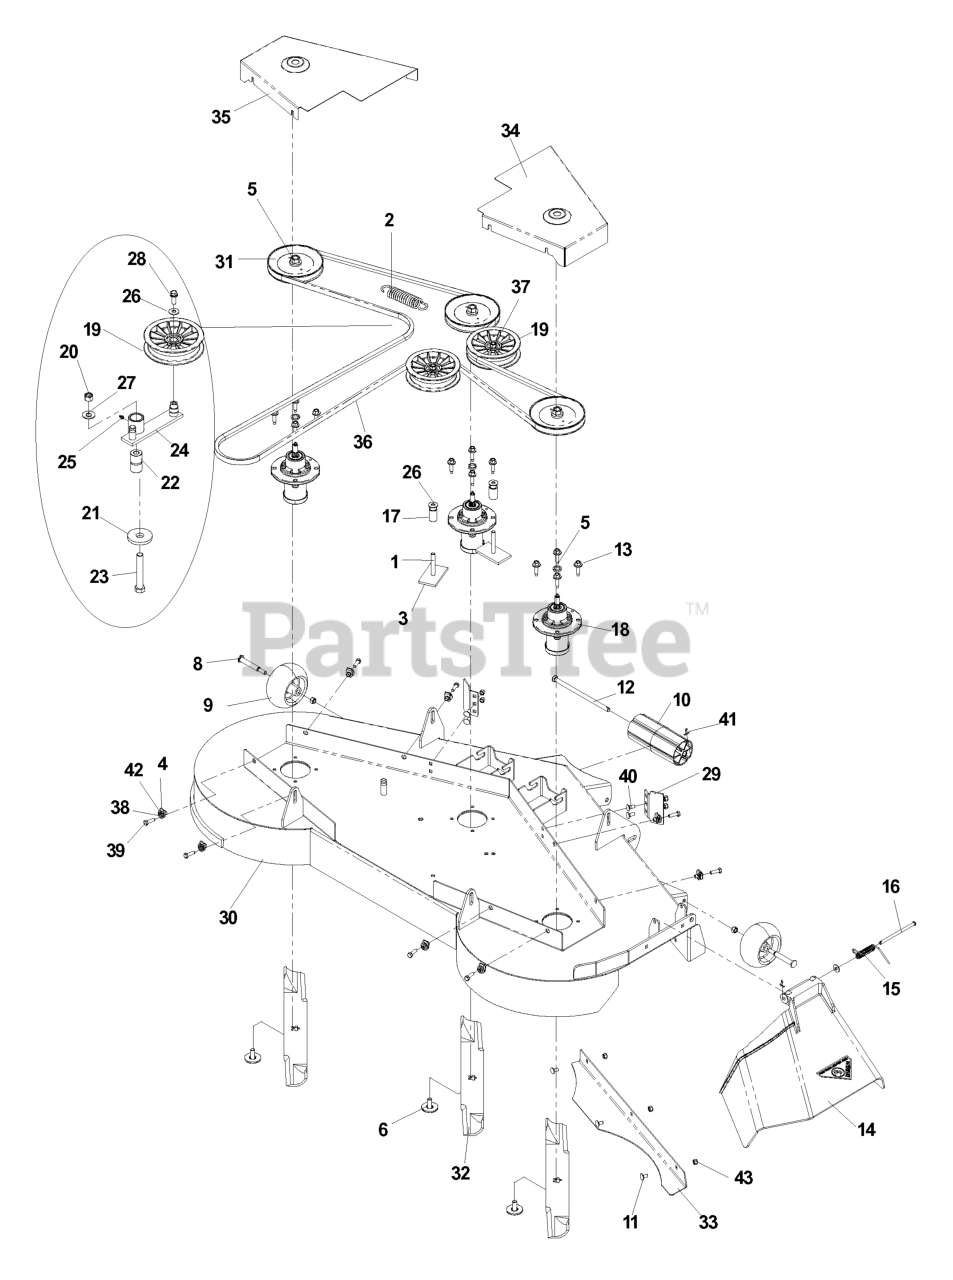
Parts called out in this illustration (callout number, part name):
1	HCS 3/8C X 3
3	SUPPORT PLATE
4	U-CLIP 5/16-18 NUT RETAINER
5	WASHER-SPACER
6	BOLT 7/16 ASM BLADE
7	LOCKNUT - 9/16
8	BOLT, SHOULDER
9	WHEEL GAGE DONUT
10	NOSE ROLLER 48"
11	CARRIAGE BOLT 5/16C X 5/8"
12	NOSE ROLLER ROD
13	WASHER HEAD SCREW
14	DISCHARGE CHUTE 61"
15	SPRING - TORSION
16	PIN-CLEVIS 5/16 DIA X 5.19 ZD
17	IDLER BUSHING
18	MANDREL.DECK.ASSEMBLY
19	IDLER
20	NUT 1/2-13 HEX NYLOC ZD
21	WASHER, SUPPORT
22	PIVOT BUSHING
23	HCS 1/2C X 3 1/4
25	ZERK
26	WASHER 3/8 FLAT
27	WASHER 1/2 FLAT
28	4CS 3/8C X 1 SERRATED HEAD
30	DECK W/DECALS 61" HUS
32	BLADE, 21"
33	CONFINEMENT PLATE 61
34	BELT SHIELD W/DECALS, 61" RT
35	BELT SHIELD W/DECALS,61" LT
36	BELT, DECK - ESTATE
37	NUT 3/8-16 NYLOC
38	WASHER.LOCK.HVY.HLCL.SPR.5/16
39	HCS 5/16C X 1
40	BOLT 5/16C X 3/4" CARRIAGE
41	RP_COTTER PIN 1/8 X 3/4
42	WASHER 5/16 FLAT
43	NUT 5/16 NYLOC
